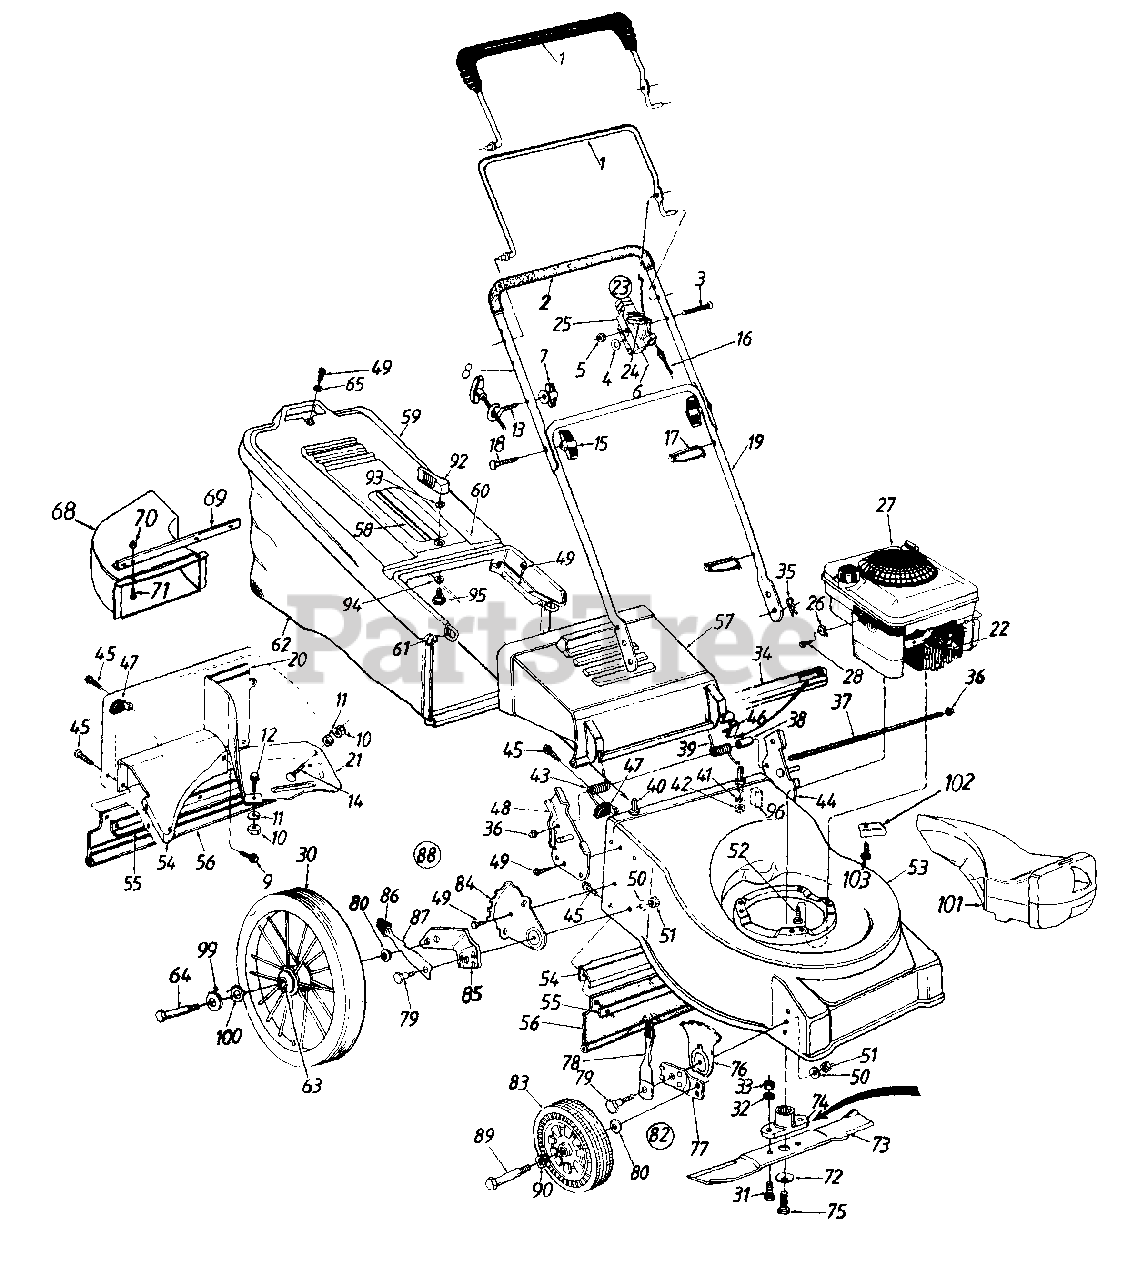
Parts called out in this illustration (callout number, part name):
2	Foam Grip
3	Oval C-Sunk Scr.
4	Spr. Wash. .66" I.D.
5	Hex L-Nut 1/4-20 Thd.
6	Throttle Cable - 55" (B&S)
7	Handle Knob 1/4-20 Thd.
10	Hex Nut 1/4-20 Thd.
11	L-Wash. 1/4" I.D.
12	Hex Bolt 1/4-20 x .85" Lg.
13	Rope Guide
14	Carr. Bolt 1/4-20 x .5" Lg.
16	Control Cable - 40.5" (B&S)
17	Cable Tie
18	Curved Hd. Bolt 5/16-18 x 2" Lg.
22	Spark Plug Boot
24	Throttle Lever
25	Throttle Body
26	Cable Clamp (B&S)
27	Engine
28	Hex Self-Tap Scr. #10-32 x .62" Lg. (B&S)
30	Wheel Ass'y. Comp.- Steel Rim
31	Hex Bolt 3/8-24 x 1"
32	L-Wash. 3/8" I.D.
33	Hex Nut 3/8-24 Thd.
34	Seal - Extrusion
35	Int. Cotter Pin 5/16" Dia.
36	Cap Speed Nut
37	Hinge Pin 17.75" Lg.
38	Spacer .255" I D.
39	Torsion Spring - L.H.
40	Shld. Pin 3/8-24 x 1.43" Lg.
41	L-Wash. 3/8" I.D.
42	Hex Jam Nut 3/8-24 Thd.
43	Torsion Spring - R.H.
46	Deflector Plug
47	Corner Plug
50	Bell-Wash. .39" I.D.
51	Hex Nut 3/8-16 Thd.
52	Hex L-Wash. Hd. Scr. 3/8-16 x 1" Lg.
57	Rear Chute Deflector
58	Hardtop Handle
59	Hardtop Bag Cover
60	Rear Catcher Frame
62	Grass Bag
63	Bearing (2 Per Wheel)
64	Shld. Bolt .5 Dia. x 2.62"
65	Fl-Wash. .281" I.D.
68	Chute Deflector
70	Hex L-Nut 1/4-20 Thd.
71	Mach. Scr. 1/4-20 x .5" Lg.
72	Bell-Wash. .46" I.D.
73	21" Blade
74	Blade Adapter Kit
75	Hex Bolt 7/16-20 x 1.5" Lg.
76	Height Ad). Plate
78	Spring Lever Ass'y. w/Knob
79	Shld. Bolt .50" Dia. x .357"
80	Bell-Wash. .38" I.D. x.88" O.D.
82	Height Adj. Ass'y. Comp.- R.H.
83	Front Wheel Ass'y. Comp.
84	Index Plate
85	Pivot Bar - R.H.
86	Spring Lever Knob
87	Spring Lever
88	Rear Height Adj. Ass'y. Comp.- R.H.
89	Front Axle Bolt
90	Wave Wash. .51" I.D. x .78" O.D.
92	Grass Catcher Locking Knob
93	Internal L-Wash. 1/4" I.D.
94	Wave Washer 3/8" I.D.
95	Shld. Bolt .342" Dia. x .268"
99	Fl-Wash. .51" I.D. x 1.373"
100	Spr. Wash. .5" I.D. x 1" O.D.
101	Mulching Plug
102	Stop Bracket
103	Hex Tap Scr. 3/8-16 x .75" Lg.
